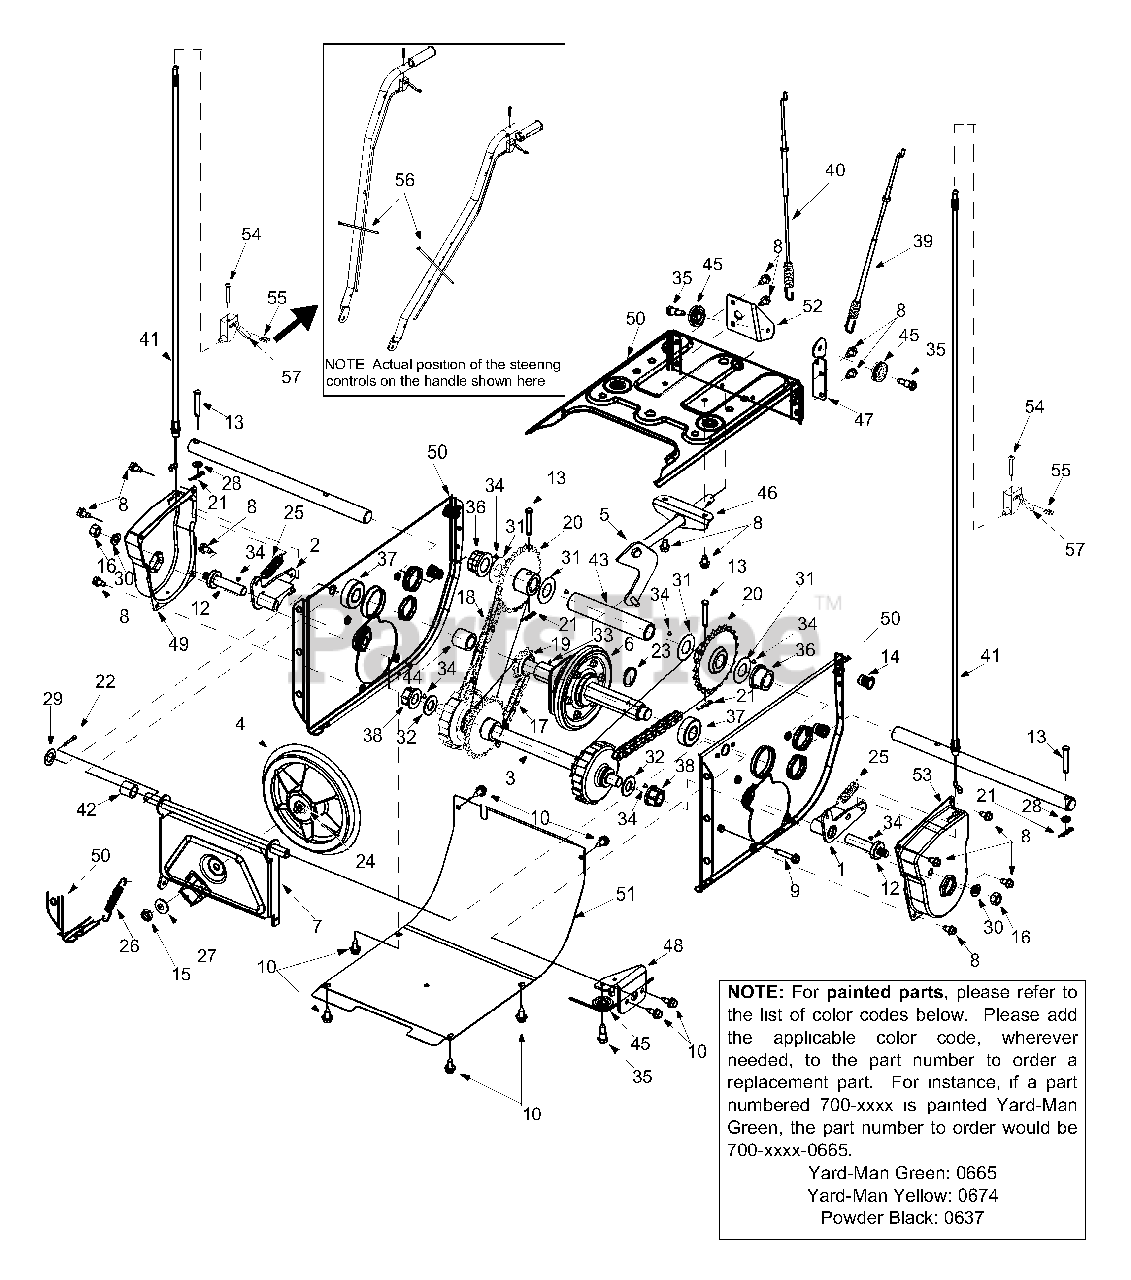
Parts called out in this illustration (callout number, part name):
1	Dogg Assembly: RH
2	Dogg Assembly: LH
3	Drive Shaft Assembly
4	Friction Wheel: Disc Assembly
6	Bearing: Friction Wheel
9	TT Screw: 1/4-20 x 1.25"
10	TT Screw: 1/4-20 x 0.625"
12	Drive Shaft: Actr.
13	Clevis Pin
14	Nut Insert
15	Jam Nut
16	Jam Nut
17	Chain
18	Chain
19	Sprocket: 10T
20	Sprocket: 23T
21	Hairpin Clip
22	Cotter Pin
23	Snap Ring
24	Loctite TM Adhesive
25	Extension Spring
26	Extension Spring
27	Spring Washer
28	Flat Washer
29	Flat Washer
30	Lock Washer
31	Flat Washer
32	Flat Washer
33	6-in-1 Lubricant
34	Grease
35	Carriage Screw
36	Hex Flange Bearing
37	Ball Bearing
38	Hex Flange Bearing
39	Auger Clutch Cable
40	Drive Clutch Cable
41	Steering Cable
42	Spacer
43	Support Tube: Axle
44	Spacer
45	Roller: Cable
55	Weld Nut
56	Cable Tie
57	Steering Control
